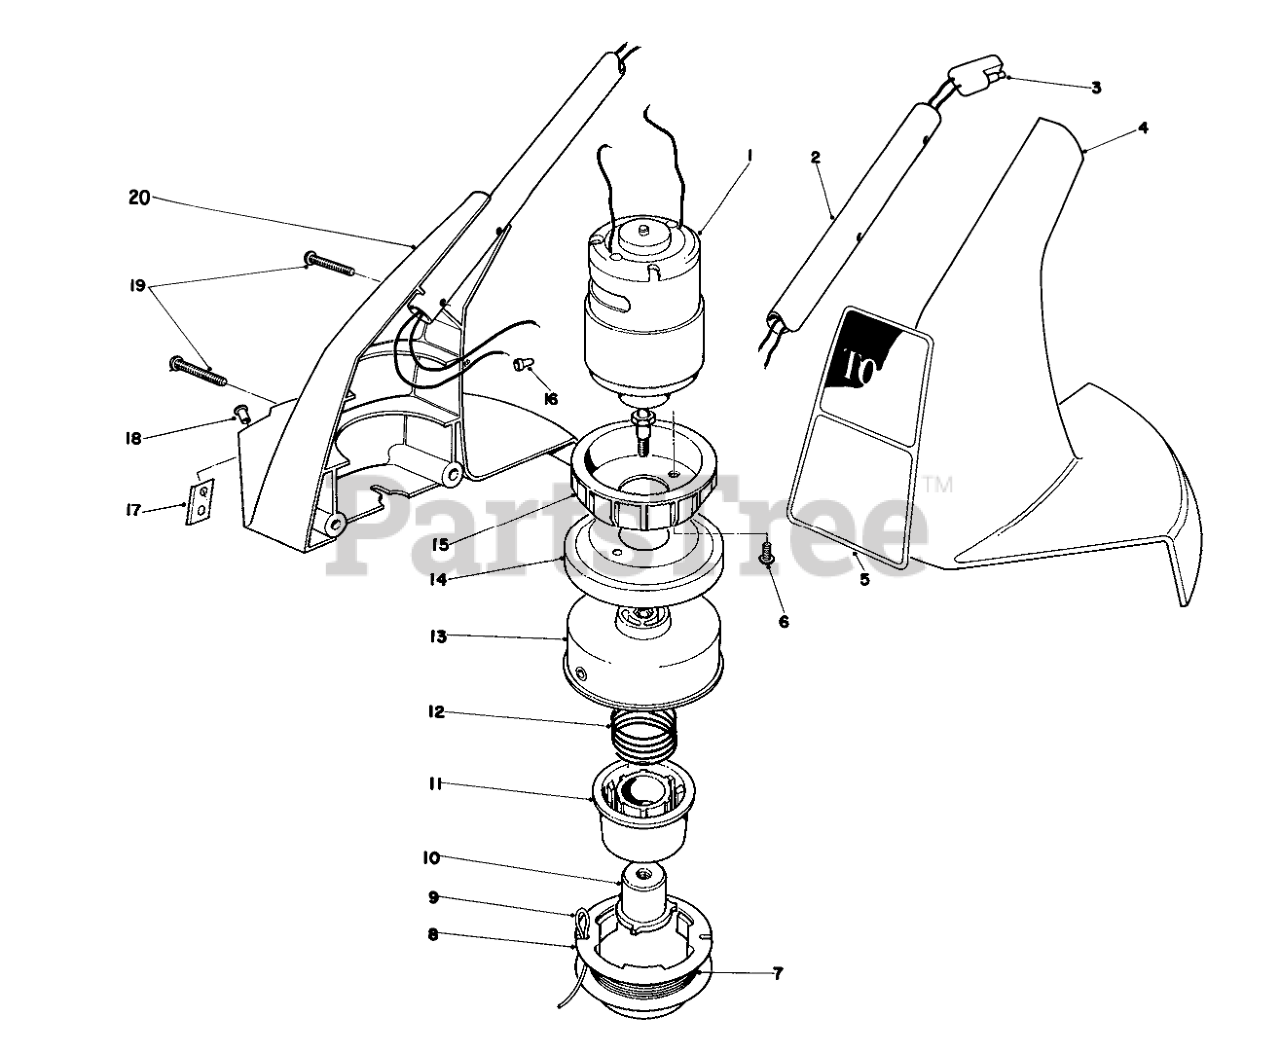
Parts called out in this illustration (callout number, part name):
1	Motor
2	EXTENSION HANDLE
3	WIRING HARNESS LOWER
4	Housing-L.H.
5	Decal-CL-700
6	Screw
7	Prewound Spool
8	SPOOL CAP
9	.040" Cutting Line in Coil
10	DRIVER
11	CORE - SPOOL
12	Spring
13	Drum w/Eyelet
14	DRUM CUP
15	Casting-Heat Sink
16	Connector
17	Knife Blade
18	Rivet
20	R.H. Motor Housing (Incl. Ref. #17&18)
